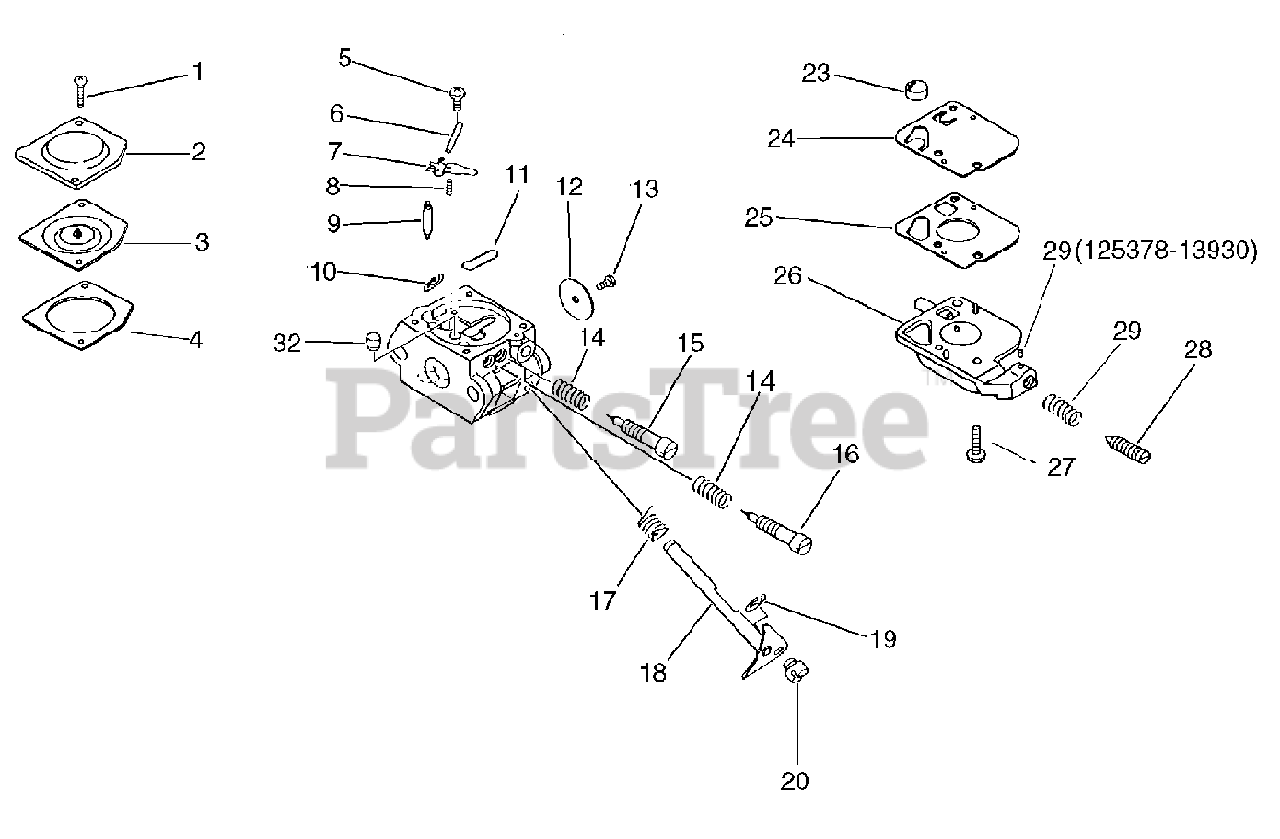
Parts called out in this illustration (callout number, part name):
2	Cover, Diaphragm
3	Diaphragm
4	Gasket, Diaphragm
6	Pin, Metering Arm
7	Lever, Metering
8	Spring, Coil
9	Valve,Inlet Needle
11	Plug, Welch
12	Valve, Throttle
14	Spring, Coil
15	Needle, Idle
16	Needle, High Speed
17	Spring, Thrt. Return
18	Shaft, Throttle
24	Diaphragm, Fuel Pump
25	Gasket, Pump
26	Cover, Pump
29	Spring,Adjust Screw
32	Nozzle, Check Valve
